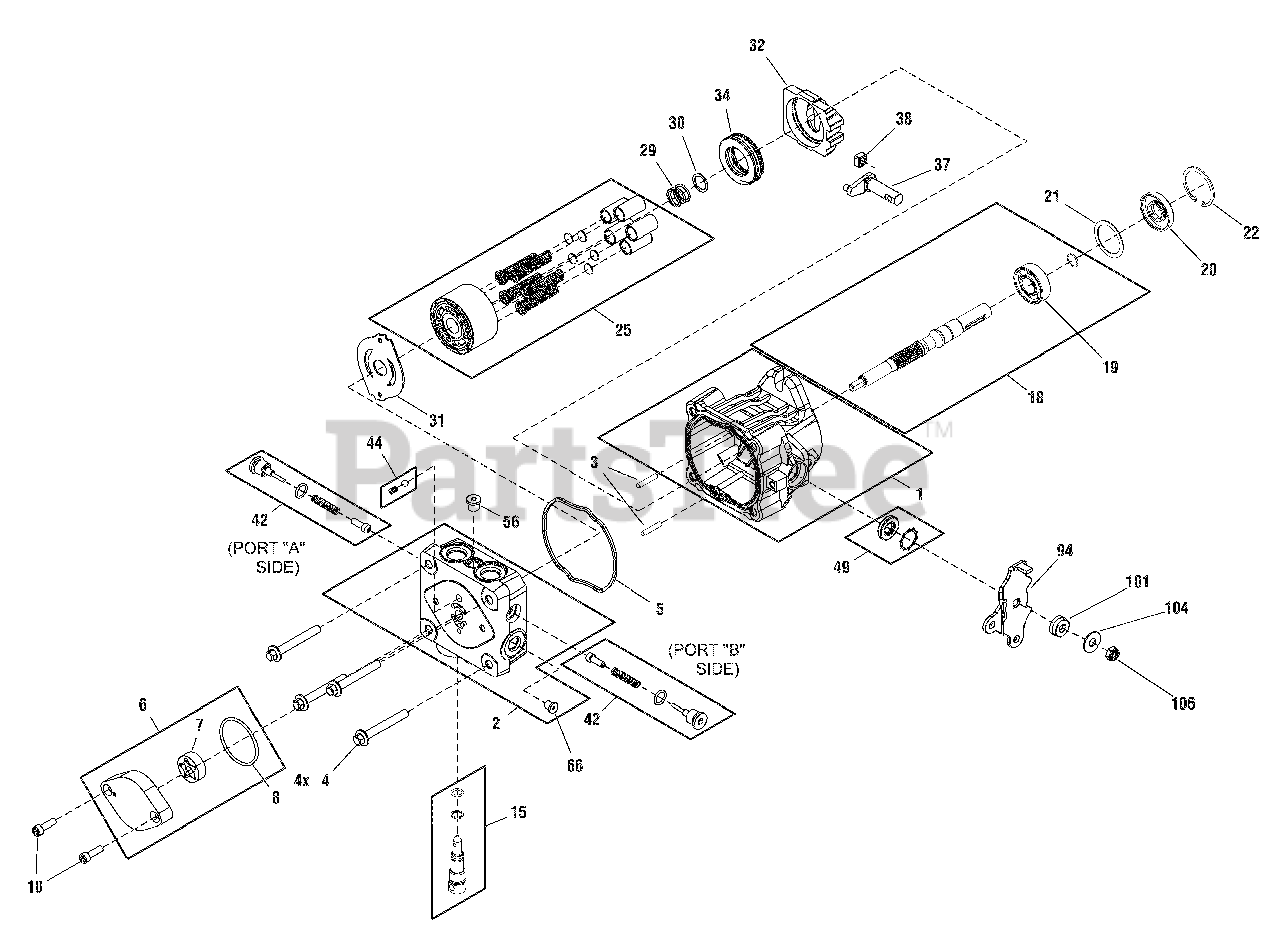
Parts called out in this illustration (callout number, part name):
1	Housing Kit
2	End Cap Kit (W/ Poppets, Standard Charge)
3	Straight Headless Pin
4	Hex Flange Bolt M8-1.25 X 60mm LG
5	Housing O-Ring
6	Charge Pump Kit (STD)
7	STD Gerotor Assy (11 cu. In/rev D-Drive)
8	O-Ring
10	Socket Head Screw M6 x 1.0-20mm Lg (STD Charge)
15	Bypass Valve Kit (Blank)
18	Pump Shaft Kit (Blind 15mm Keyway W/ Std Charge)
20	Lip Seal 17 x 40 x 7 PTC
21	Spacer
22	Retaining Ring
25	Cylinder Block Kit
29	Block Spring
30	Block Thrust Washer
31	Valve Plate (Steel N-Tec:Black)
32	Swashplate
34	Ball Thrust Bearing
37	Trunnion Arm, Tapered Square
38	Slot Guide
42	Check Valve Kit (0.031"Orifice)
44	Charge Relief Valve Kit (1/4" Plastic Ball & Spring)
49	Trunnion Seal / Retainer Kit
56	Straight Thread Plug
66	PLUG, 5/16" SAE
94	Arm, Control
101	Spacer RTN
106	Nut, Hex Lock 5/16-24 UNF
110	Kit, RTN, STD
